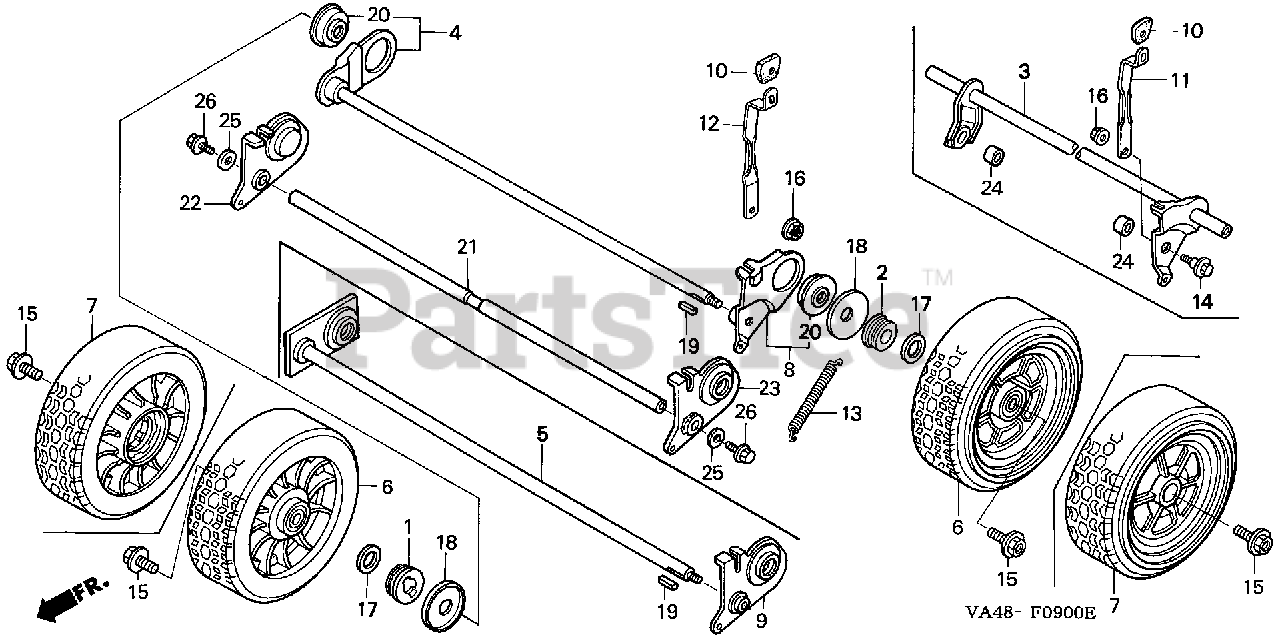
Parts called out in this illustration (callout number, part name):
1	HOLDER, R. RATCHET
2	HOLDER, L. RATCHET
5	SHAFT, RR. AXLE
7	WHEEL, PROPELLED (8") (NH166)
9	ARM, RR. ADJUSTER
10	GRIP, ADJUSTER
10	GRIP, ADJUSTER *NH105* (MAT BLACK)
12	PLATE, RR. ADJUSTER
13	SPRING, RR. BALANCER
15	BOLT, WHEEL
16	NUT, SELF-LOCK (8MM)
17	WASHER (16MM)
18	WASHER, WHEEL
19	KEY (4X4X11)
21	SHAFT, RR. AXLE
22	ARM, R. RR. ADJUSTER
23	ARM, RR. ADJUSTER
25	WASHER, RR. ENGINE MOUNTING
26	BOLT, FLANGE (8X16) Use from Engine SN 1000016.
NI	TIRE (8 INCH)
